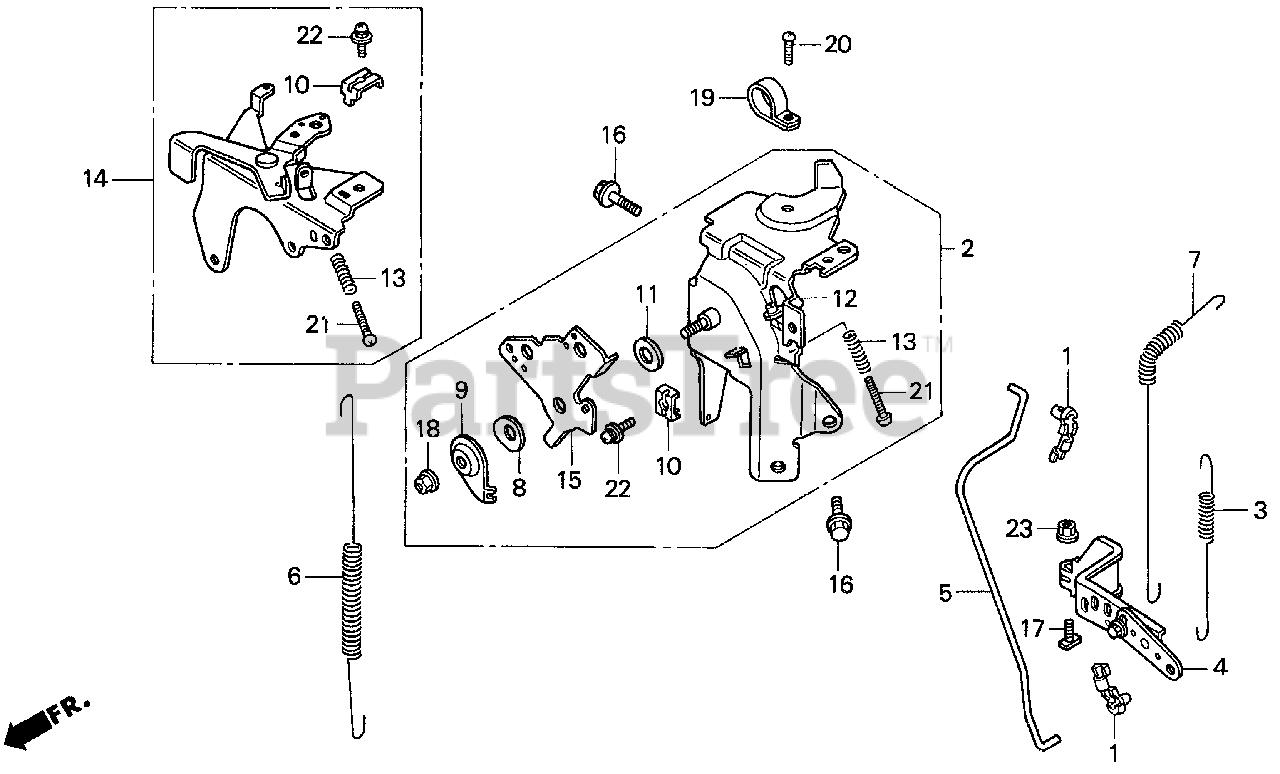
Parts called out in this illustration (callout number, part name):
1	JOINT, ROD
2	CONTROL ASSY. (REMOTE)
3	SPRING, STARTER
4	ARM, GOVERNOR
5	ROD, GOVERNOR
6	SPRING, GOVERNOR
7	SPRING, THROTTLE RETURN
8	SPRING, LEVER
9	WASHER, CONTROL LEVER
10	HOLDER, CABLE
11	SPACER, CONTROL LEVER
12	BASE, CONTROL
13	SPRING, CONTROL ADJUSTING
14	STAY ASSY., CHOKE CONTROL (REMOTE)
15	LEVER, WIRE
16	BOLT, FLANGE (6X12) (CT200)
17	BOLT, GOVERNOR ARM
18	NUT, SELF-LOCK (6MM)
19	CLAMP (D17.5)
20	SCREW, PAN (5X12)
21	SCREW, PAN (5X25)
22	SCREW-WASHER (5X16)
23	NUT, FLANGE (6MM)
